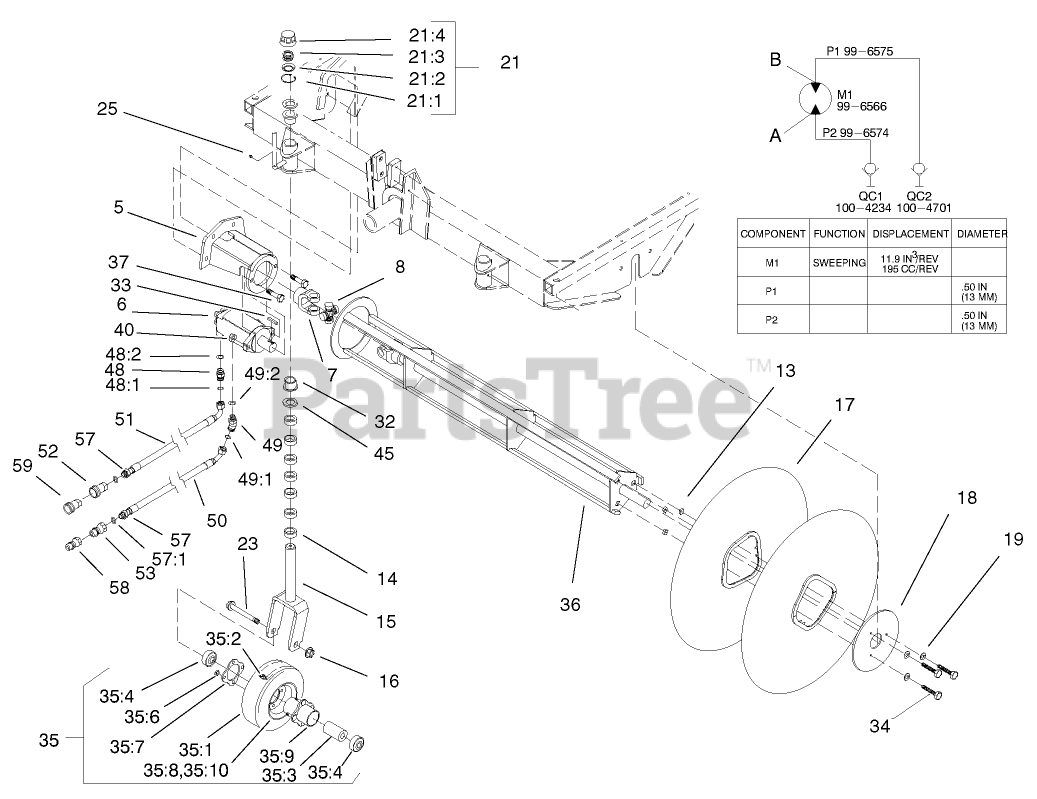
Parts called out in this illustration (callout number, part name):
5	HYD MOTOR MOUNT ASM
6	MOTOR-HYDRAULIC
7	YOKE-KEYED
8	CROSS-YOKE
13	RETAINER-NUT
14	SPACER
15	CASTOR FORK ASM
16	NUT-LOCK, NI
17	ELEMENT-BRUSH, POLY
17	ELEMENT-BRUSH, WIRE (OPTIONAL)
18	PLATE-RETAINER, BRUSH
19	WASHER-LOCK
21	HOC CAP ASM
21:1	RING-RETAINING
21:2	WASHER-CAP
21:3	SPRING-COMPRESSION
21:4	CAP-HOC
23	SCREW-HH
25	FITTING-GREASE
32	Bushing
33	KEY-STEP
34	SCREW-HH
35	WHEEL ASM
35:2	TUBE-INNER (W/VALVE)
35:3	SPACER-BEARING, INNER
35:4	BEARING
35:6	NUT-HHF
35:7	PLATE
35:8	RIM-WHEEL, HALF
35:10	RIM-WHEEL, HALF
36	ROTOR FRAME ASM
37	SCREW-HH
40	SCREW-HH
45	WASHER
48	FITTING-STRAIGHT
48:1	O-RING
48:2	O-RING
49	FITTING-HYD-45
49:1	O-RING
49:2	O-RING
50	HOSE ASM
51	HOSE ASM
52	COUPLER-FACE, FLUSH
53	NIPPLE-CONNECT, PRESSURE
57	ADAPTER-HYD
57:1	O-RING
58	DISCONNECT-QUICK, MALE
59	DISCONNECT-QUICK, FEMALE
